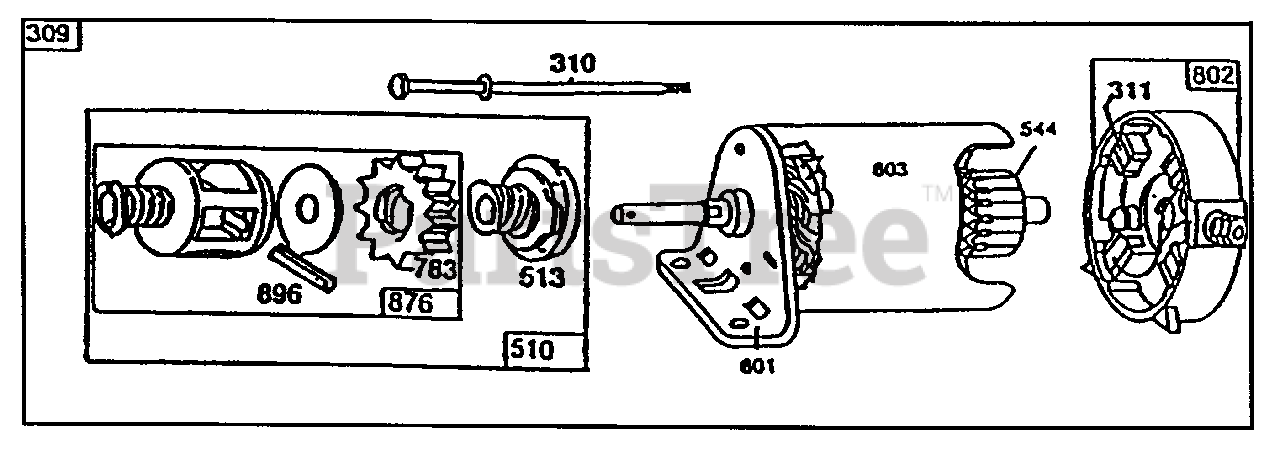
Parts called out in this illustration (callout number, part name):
309	Assembly Motor & Drive
310	Assembly-Thru bolt
311	Assembly-Brush
510	Assembly-Drive (Incl. Ref. #513, 783, 876 & 896)
513	Assembly-Clutch
544	Assembly-Armature
801	Assembly-End Cap
802	Assembly-Commutator, End Cap
803	Assembly-Housing (3-21/32" Long)
876	Kit-Retainer
896	Pin-Roll
